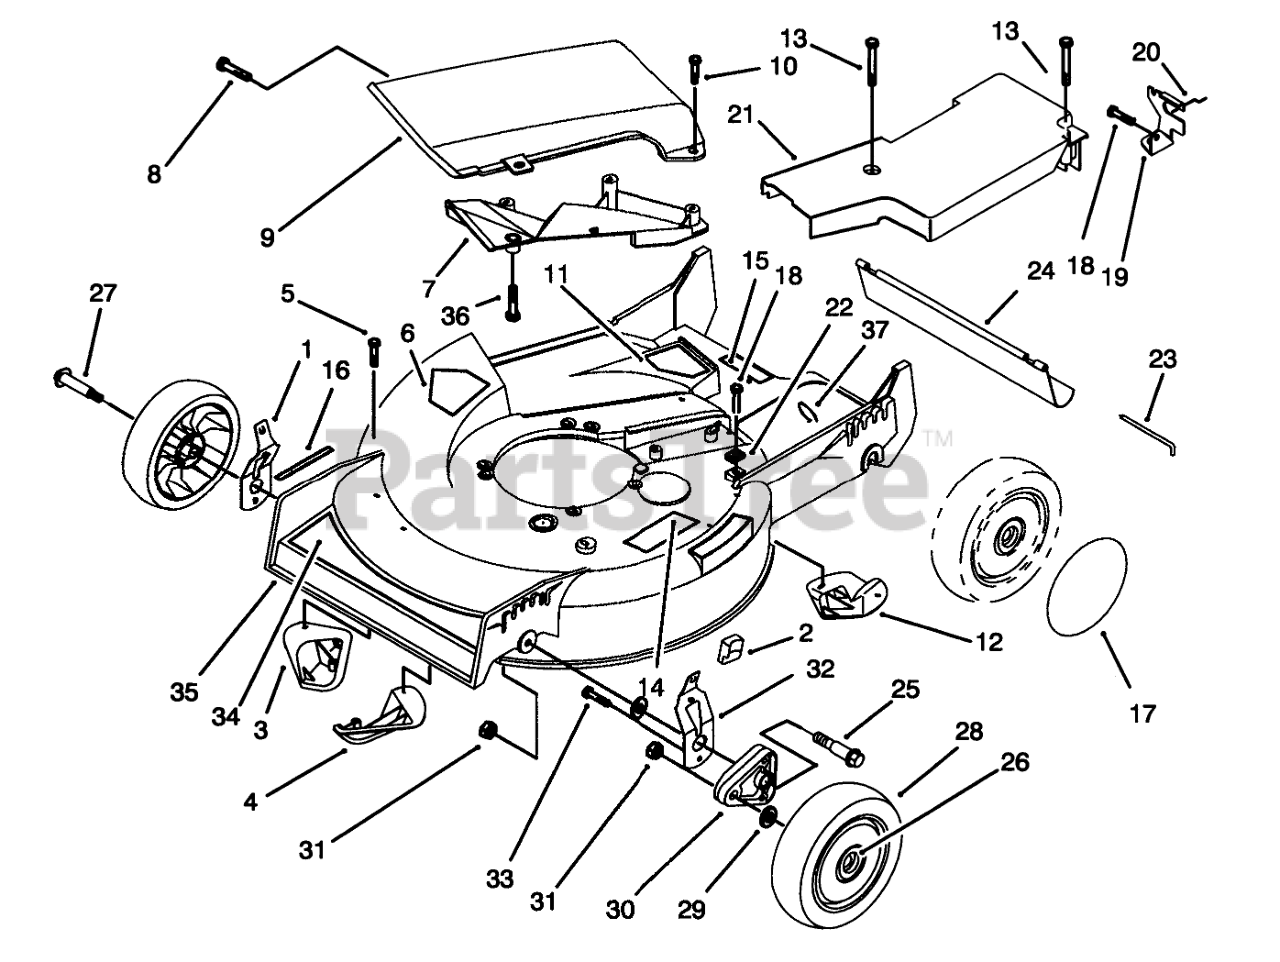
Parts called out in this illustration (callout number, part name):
1	RH SPRING ARM ASSEMBLY
2	KNOB-ARM
3	KICKER-FRONT
4	KICKER-RH
5	SCREW-PPH
6	DECAL-DANGER
7	Deflector-Recycler
8	SCREW AND WASHER ASM
9	Recycler Cover Assembly (Incl. Ref. #7 & 36)
10	SCREW-HWH
11	DECAL - DANGER
12	KICKER-REAR
13	SCREW-HHFTF
14	DECAL-INSTRUCTION, SAFETY
15	DECAL-WARNING
16	DECAL - HOC
17	WHEEL COVER
18	SCREW-HWHTF
19	Bracket-Adj. Trac
20	RETAINER-CABLE
21	BELT COVER ASM
22	CLAMP-CABLE
23	ROD-SHIELD
24	SHIELD-TRAILING
25	BOLT-SHOULDER
26	BUSHING
27	BOLT-WHEEL
28	Wheel & Tire Assembly (Incl Ref. #26)
29	WASHER
30	ARM-PIVOT, FRONT
31	NUT-LOCK
32	LH SPRING ARM ASSEMBLY
33	SCREW-HWH
34	DECAL - DECK
35	Housing (Incl. Ref. #3-6, 11, 12, & 14-16 pg. 1) (Incl. Ref. #6, & 7 pg.3)
36	Screw-Plastite
37	TIE-CABLE
